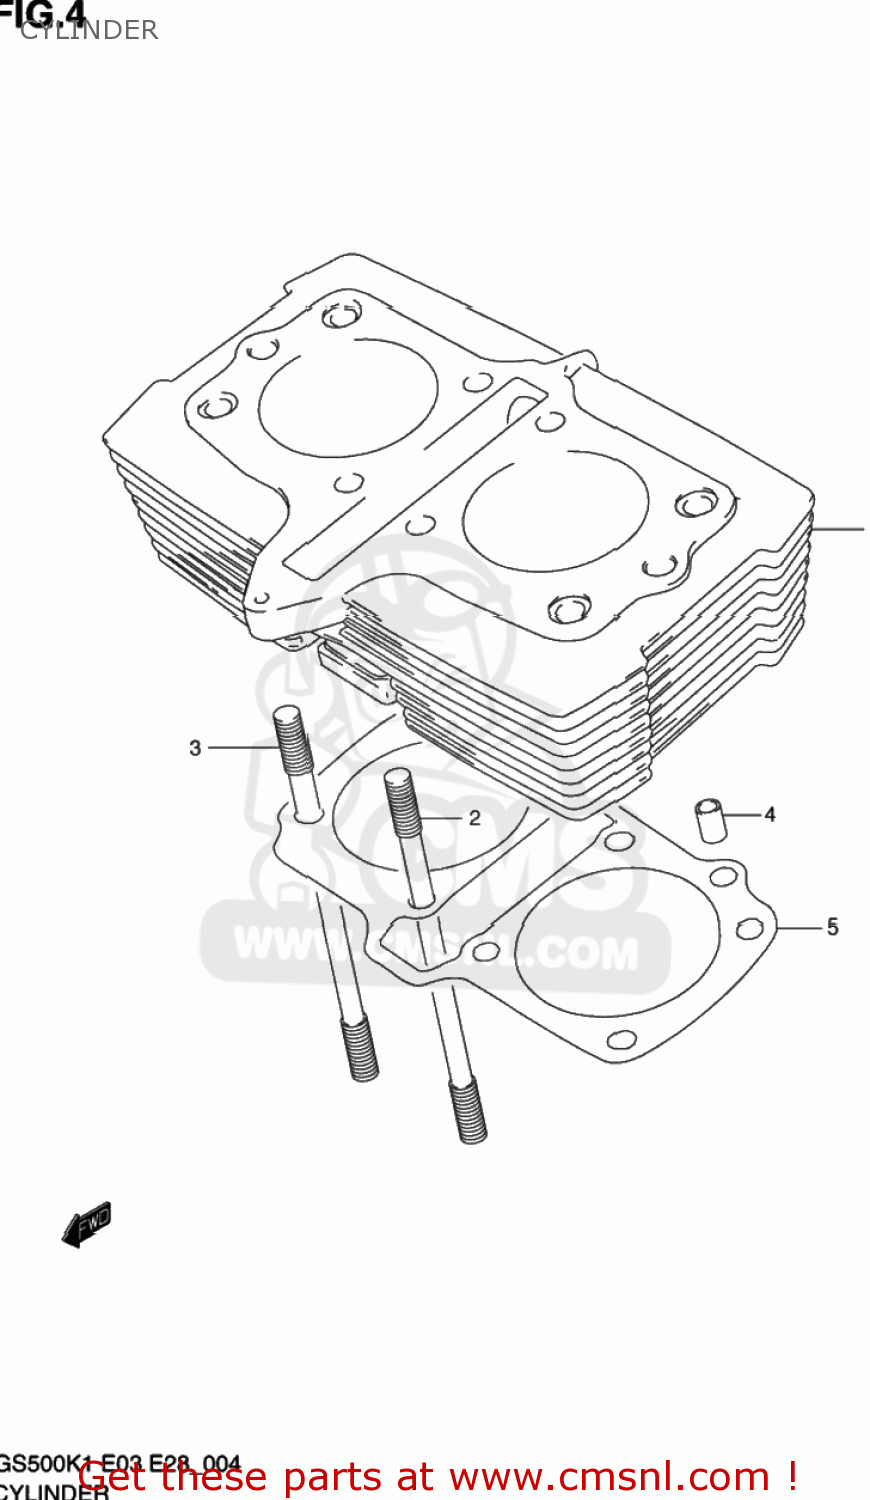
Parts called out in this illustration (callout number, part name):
1	CYLINDER
2	BOLT,STUD
3	BOLT,STUD
4	PIN
5	GASKET,CYLINDER (NAS)
